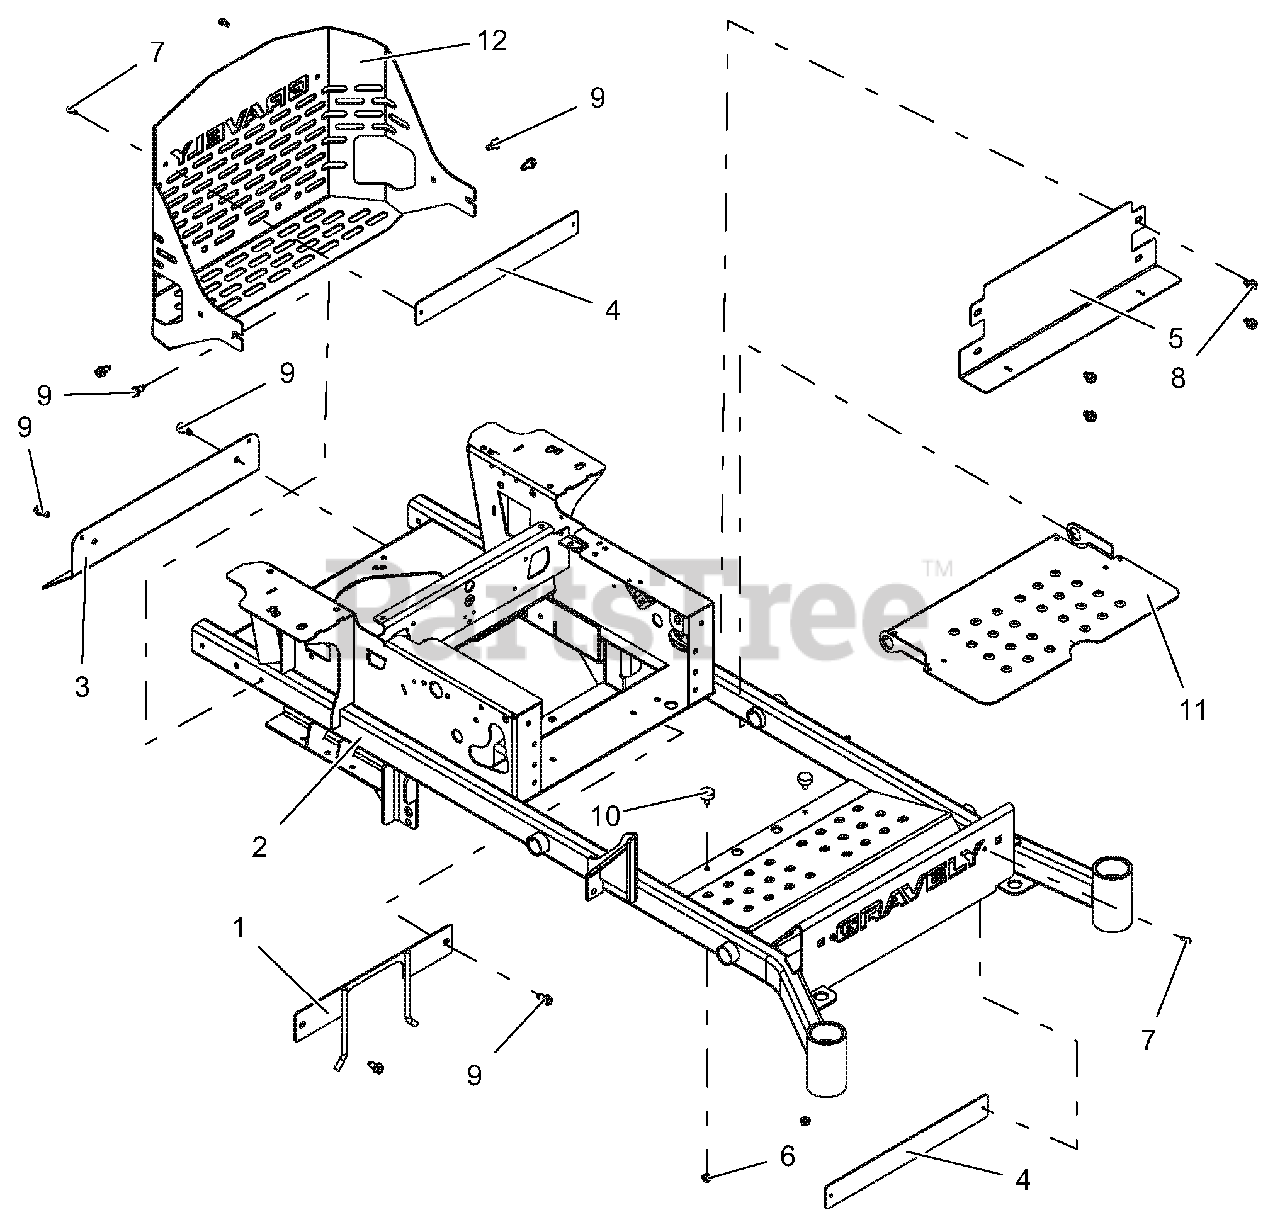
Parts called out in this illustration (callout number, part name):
1	WLDMT, PTO BELT FINGER-BLACK
2	48-52" MAIN FRAME W/SAFETY DECALS
3	SHIELD, MUFFLER HEAT-BLACK
4	PLATE, BUMPER 2.00 x 16.50 - BLK
5	PLATE, PT/PT100 KICK-RED
6	@NUT-SPNLK-FLG .312-18 YWZC
7	SCR-TAP .25-20X.50 HWH TR YWZ
8	SCR-TAP .38-16X.50 HWH TR YWZ
9	SCR-TAP .38-16X.75 HWH TR YWZ
10	BUMPER, RUBBER
11	FOOT, PLATE W/SAFETY DECALS
12	REAR BUMPER W/SAFETY DECALS
